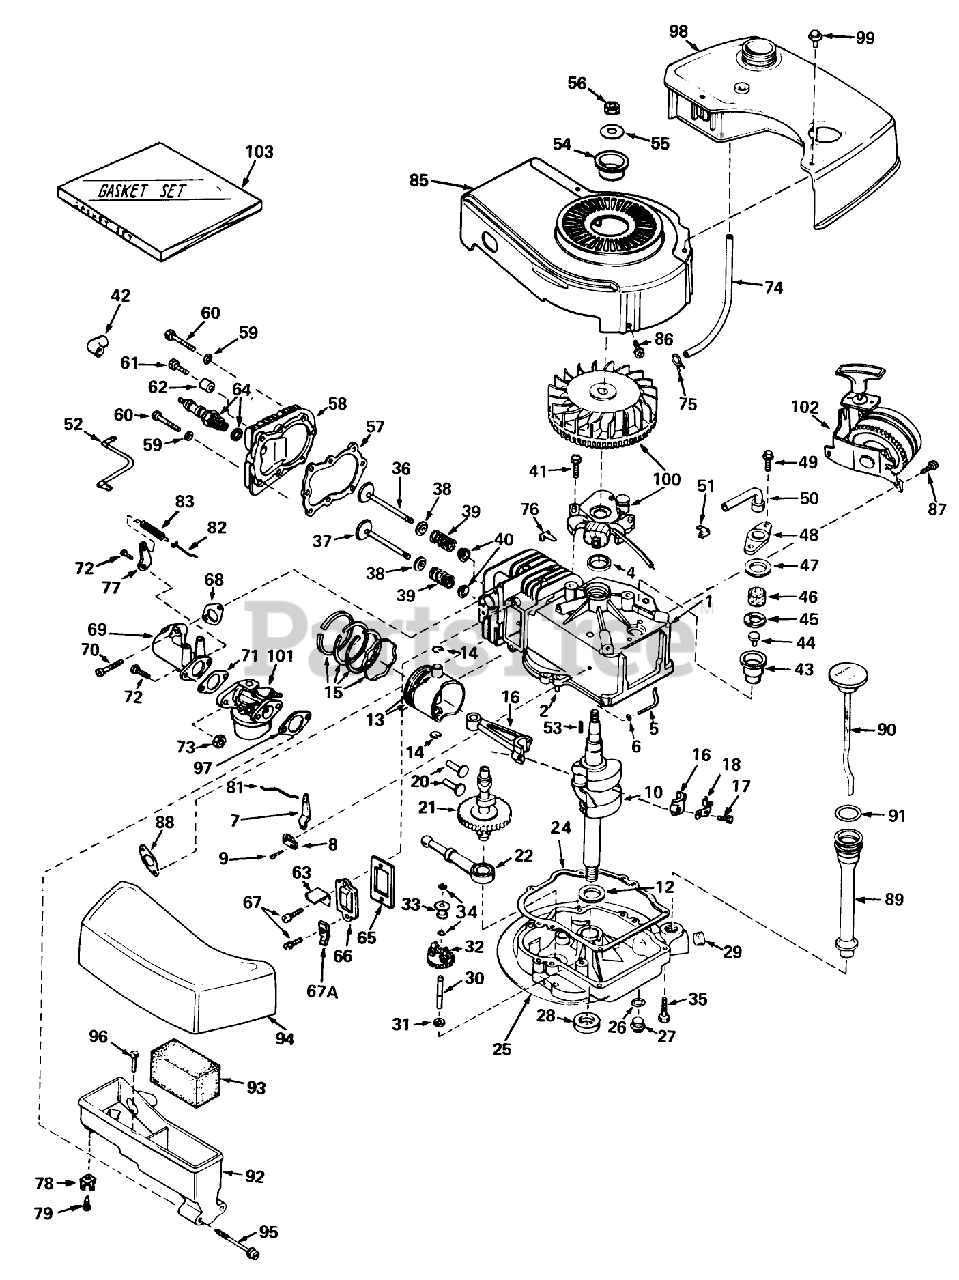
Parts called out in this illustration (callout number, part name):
1	Cylinder Assembly (Incl. Nos. 2, 4 87)
2	Pin-Dowel
4	Seal-Oil
5	Rod, Governor (Incl. No. 36)
6	Washer-Flat
7	Governor Lever
8	Clamp-Lever, Governor
9	Screw
10	Crankshaft
12	Washer-Thrust
13	Piston Pin Assembly (Incl. 2 of No. 14)(Std.)
13	Piston Pin Assembly (Incl. 2 of No. 14)(.010 Oversize)
13	Piston Pin Assembly (Incl. 2 of No. 14)(.020 Oversize)
14	Ring-Retaining, Piston Pin
15	Ring Set-Piston Std.
15	Ring Set-Piston .010 oversize
15	Ring Set-Piston .020 oversize
16	Rod Assembly, Connecting (Incl. Nos. 17 18)
17	Connecting Rod Bolt
18	Plate Lock
20	Lifter-Valve
21	Camshaft(Mech.Comp. Release)
22	Oil Pump ASM
24	Gasket, Mounting
25	Flange Assembly, Mounting (Incl. #27, 28, 29 30)
26	Gasket-Oil Drain
27	Plug Oil Drain
28	Seal-Oil
29	Plug Oil Drain
30	Shaft-Governor
31	Washer-Flat
32	Gear Assembly, Governor
33	Spool, Governor
34	Ring-Retaining
35	Screw (1/4-20 x 1-1/4)
36	Valve, Intake (Incl. Ref. #38, 39 40) (Std.)
36	Valve, Exhaust (1/32" Oversize) (Incl. Nos. 8, 9 10)
37	Valve, Exhaust (Standard) (Incl. Nos. 8, 9 10)
37	Valve, Exhaust (1/32" Oversize) (Incl. Nos. 8, 9 10)
38	Cap-Upper Valve Spring
39	Spring-Valve
40	Cap-Valve, Spring
41	Screw
42	Cover-Spark Plug
43	Body Breather Tube
44	Valve Check
45	2000A37 WIZARD ROTA
46	Element-Breather
47	Gasket-Breather
48	Cover Breather
49	Screw, Hex Hd. w/Conical
50	Tube, Breaker
51	Clip, Breather
52	Wire, Ground
53	Key Flywheel
55	Washer
56	Hex Nut
57	Oil Fill Tube
58	Head Cylinder
59	Washer
60	Screw
61	Screw Hex Hd. Cap
62	Space
63	Retainer Clip
64	Plug, Spark (J17LM or equiv.)
65	Gasket-Breather
66	Cover-Valve
67	Screw
67A	Terminal
68	Gasket, Intake
69	Pipe, Intake
70	Screw (1/4-20 x 1)
71	Gasket-Carburetor
73	Nut and Lock Washer (1/4-28)
74	Line, Fuel
75	Clamp-Line, Fuel
76	Clip-Wire
77	Lever-Adjusting, R P M
78	Terminal
79	Screw (8-32 x 3/8)
81	Link Governor
82	Link Governor Spring
83	Spring Governor
85	Housing, Blower
86	Screw
87	Screw (1/4-20 x 1/2)
88	Gasket Exhaust
89	Tube, Oil Filler
90	Dipstick, OiI (Incl. No. 91)
91	O-Ring
92	Body Air Cleaner
93	Filer, Air
94	Cove, Air Cleaner
95	Screw Fil Hd.
96	Screw, Hex Hd.
97	Gasket-Air Cleaner
98	Tank Fuel
99	Screw (10-32 x 35/64)
100	LEVER
101	Carburetor
102	Starter, Side Mount
103	53024/VAR.16HP O/P
